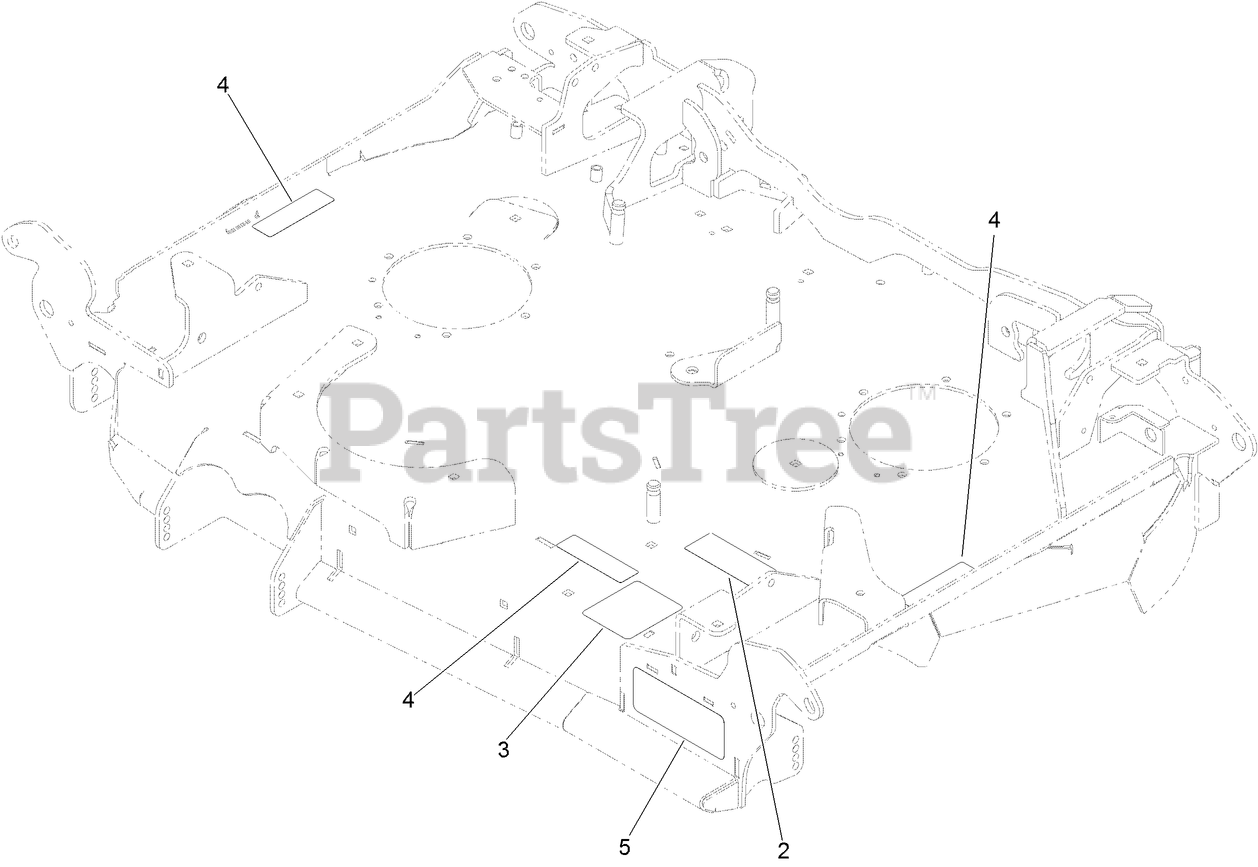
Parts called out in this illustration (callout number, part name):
2	DECAL-ROUTING, BELT
3	DECAL-ROLLER, ANTI-SCALP
4	DECAL-COVER, MISSING
